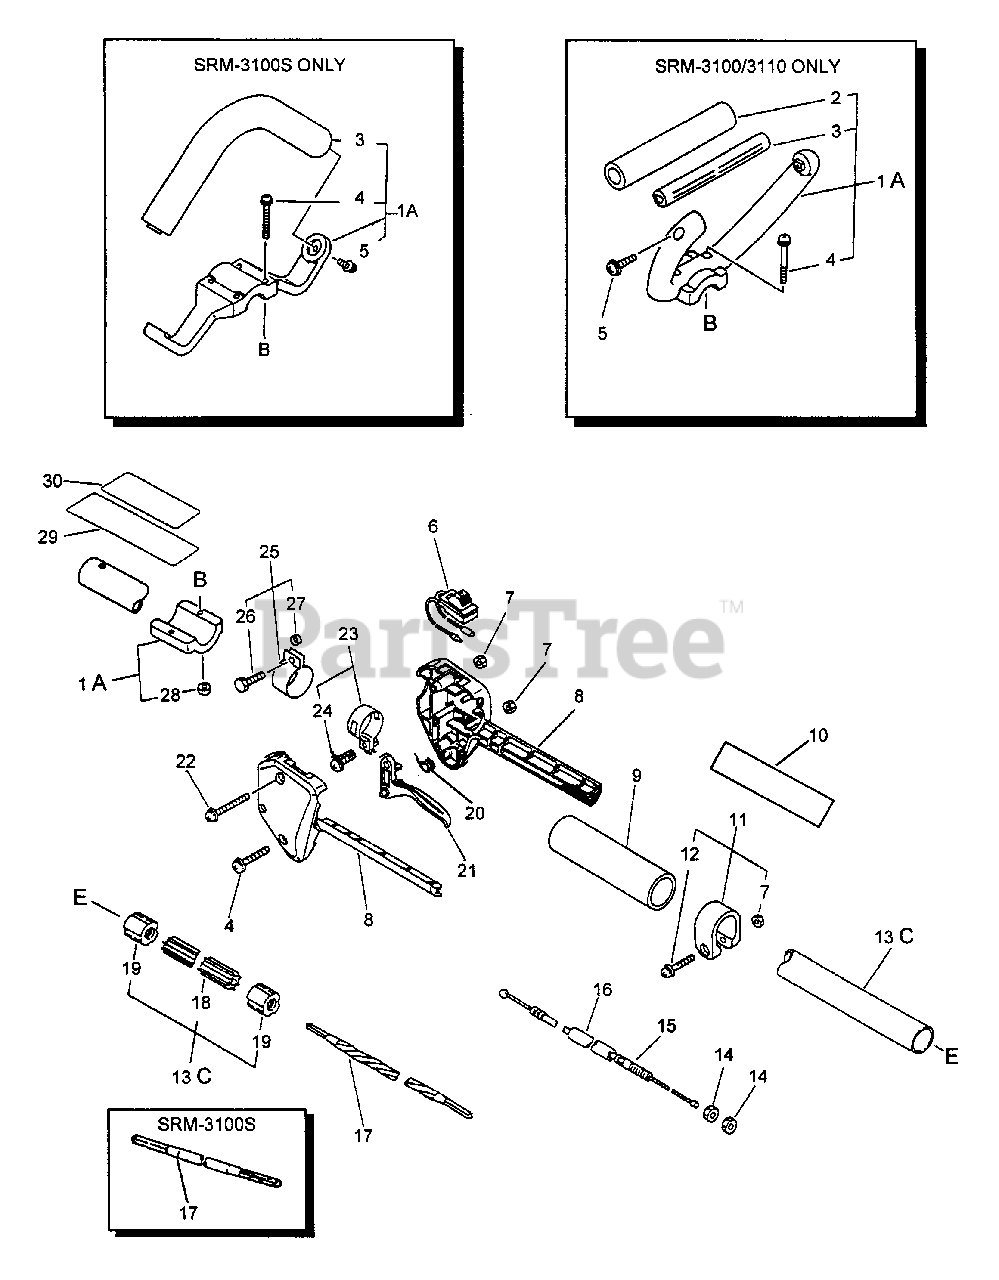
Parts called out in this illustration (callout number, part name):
1	LOOP HANDLE ASSY
2	GRIP, HANDLE
3	HANDLE
4	SCREW 5×35
4	BOLT M5×35
5	SCREW 5×30
5	SCREW 5×14
6	SWITCH, ON-OFF
7	NUT M5
8	HANDLE KIT, CONTROL
9	GRIP, HANDLE
10	LABEL - ALIGNMENT
11	CLAMP KIT
12	SCREW 5×28
13	MAIN PIPE ASSY
13	PIPE, MAIN
15	CABLE, THROTTLE
16	TUBE - VINYL
17	DRIVESHAFT - FLEXIBLE L= 1522
17	MAINSHAFT
18	LINER, FLEXIBLE 21.6×1420
20	SPRING, TORSION
21	TRIGGER, THROTTLE
22	SCREW 5×25
23	CLAMP KIT
24	SCREW 5×14
25	HOOK
26	BOLT 5×18
27	SPACER, GUARD
28	NUT M5
29	LABEL, CAUTION
30	LABEL, CAUTION
